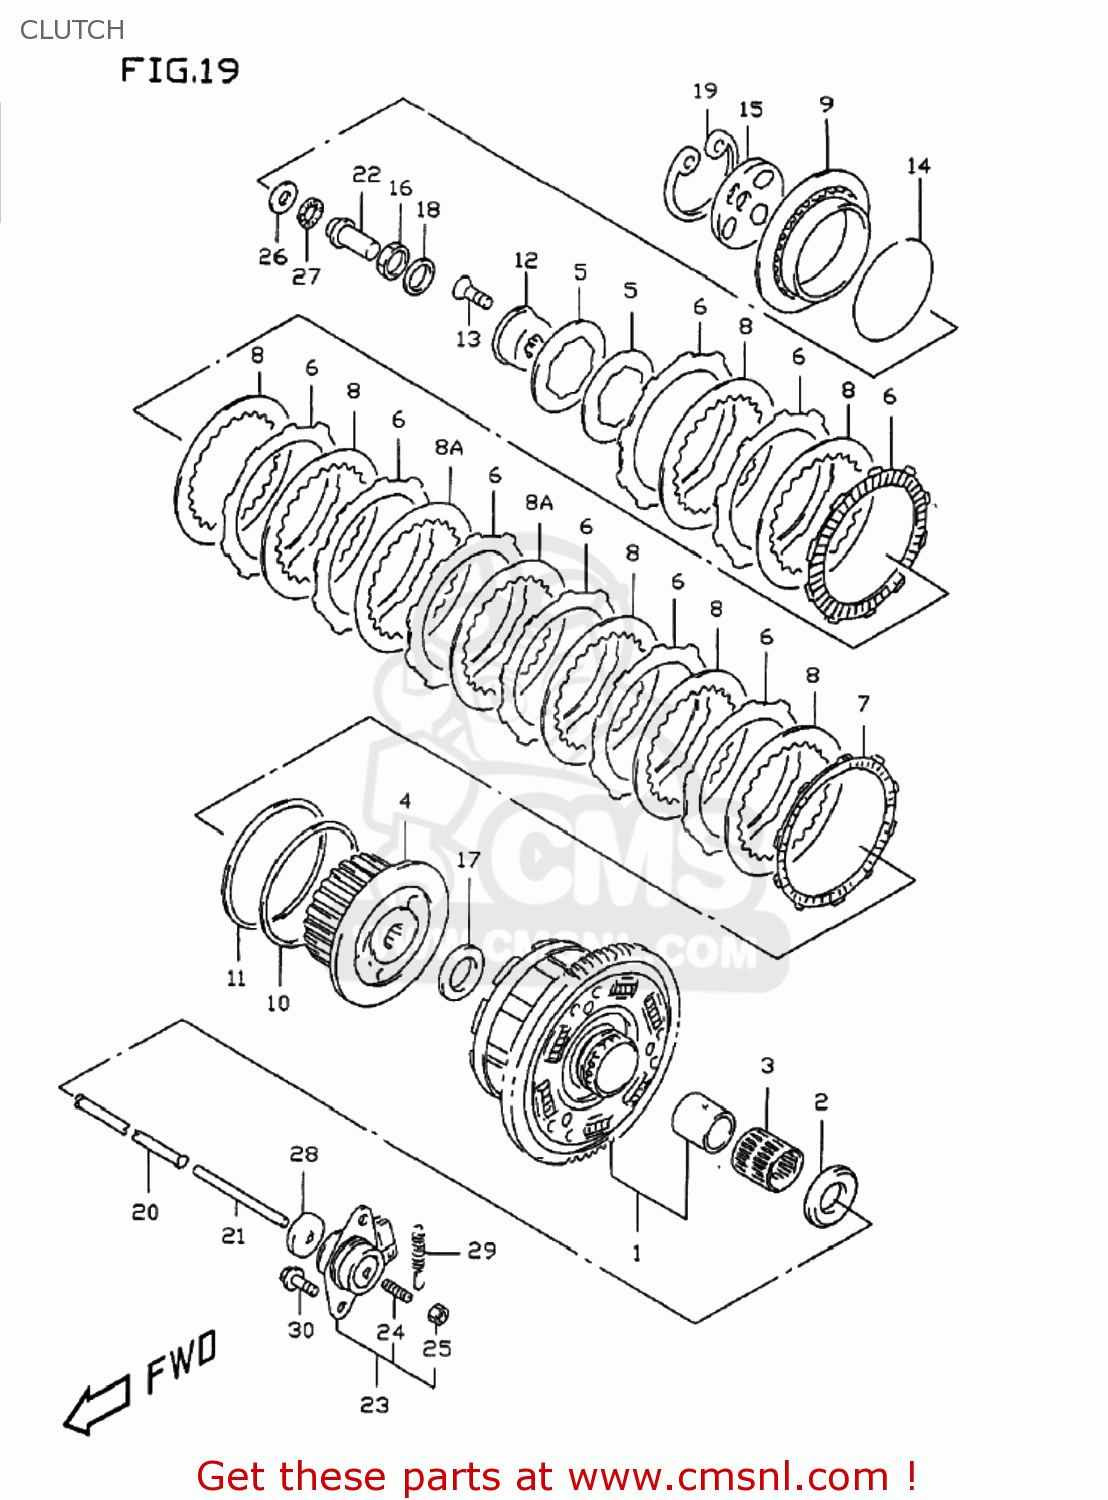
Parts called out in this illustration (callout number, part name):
1	GEAR ASSY,PRI DRIVEN
2	WASHER(25X54X2.5)
3	BEARING(35X40X35.8)
4	HUB,CLUTCH SLEEVE
5	SPRING,CLUTCH
6	PLATE,CLUTCH DRIVE
7	PLATE,CLUTCH DRIVE
8	PLATE,CLUTCH DRIVEN NO.1
8A	PLATE,CLUTCH DRIVEN NO.2
9	DISC,CLUTCH PRESSURE
10	SEAT,CLUTCH PLATE WAVE WASHER
11	WASHER,CLUTCH PLATE WAVE
12	HOLDER,CLUTCH SPRING
13	SCREW,CLUTCH SPRING HOLDER
14	SEAT,CLUTCH SPRING
15	LIFTER,CLUTCH PRESSURE DISC
16	NUT
17	WASHER
18	WASHER
19	CIRCLIP
20	ROD,CLUTCH
21	ROD,CLUTCH PUSH,L
22	PIECE,CLUTCH PUSH
23	SCREW ASSY,CLUTCH RELEASE
24	SCREW(6X25)
25	NUT
26	WASHER(15.5X28X1)
27	BEARING(15X28X2)
28	SEAL,OIL(6X34X5.5)
29	SPRING
30	BOLT
